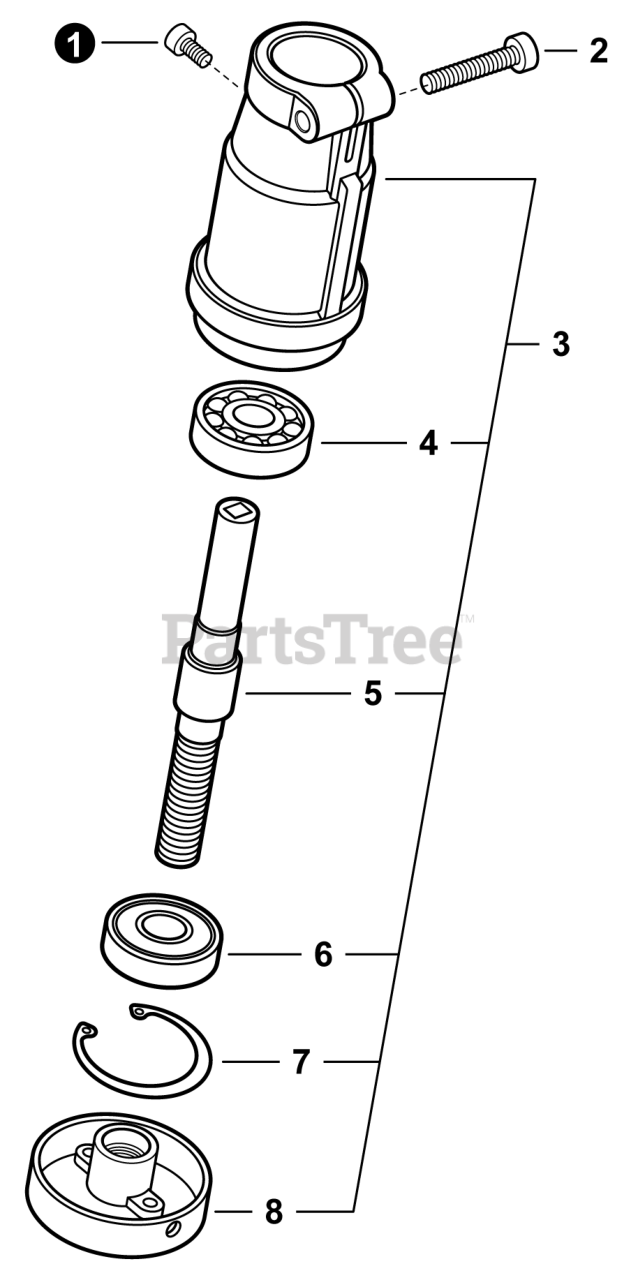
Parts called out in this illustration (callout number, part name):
1	BOLT, TORX 4x8
2	BOLT, TORX 5x25
3	GEAR CASE ASSY
4	BEARING, BALL 6200
5	SHAFT, GEAR
6	BEARING, BALL 6200
7	E-RING 30
8	PLATE, ADAPTOR - UPPER
